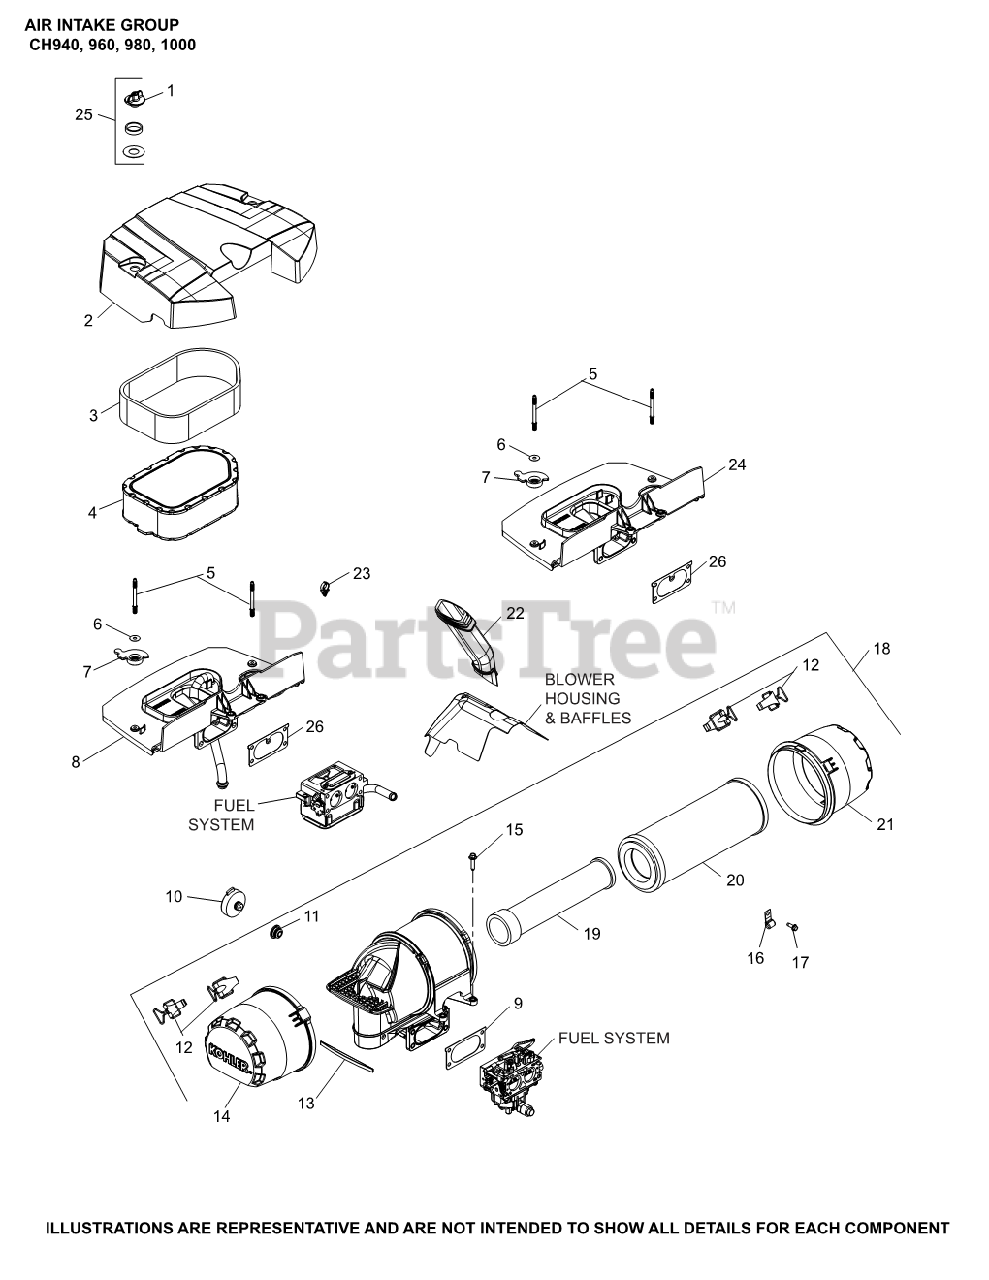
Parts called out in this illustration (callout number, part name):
1	KNOB, COVER
2	COVER, AIR CLEANER
3	ELEMENT, PRE-CLEANER
4	ELEMENT, AIR FILTER (LPAC)
5	STUD, AIR CLEANER BASE
9	GASKET, AIR CLEANER ELBOW
15	SCREW, FLG M6X1.0X25
24	KIT, AIR CLEANER BASE - (#6209440S)
25	KIT, KNOB W/SEAL
